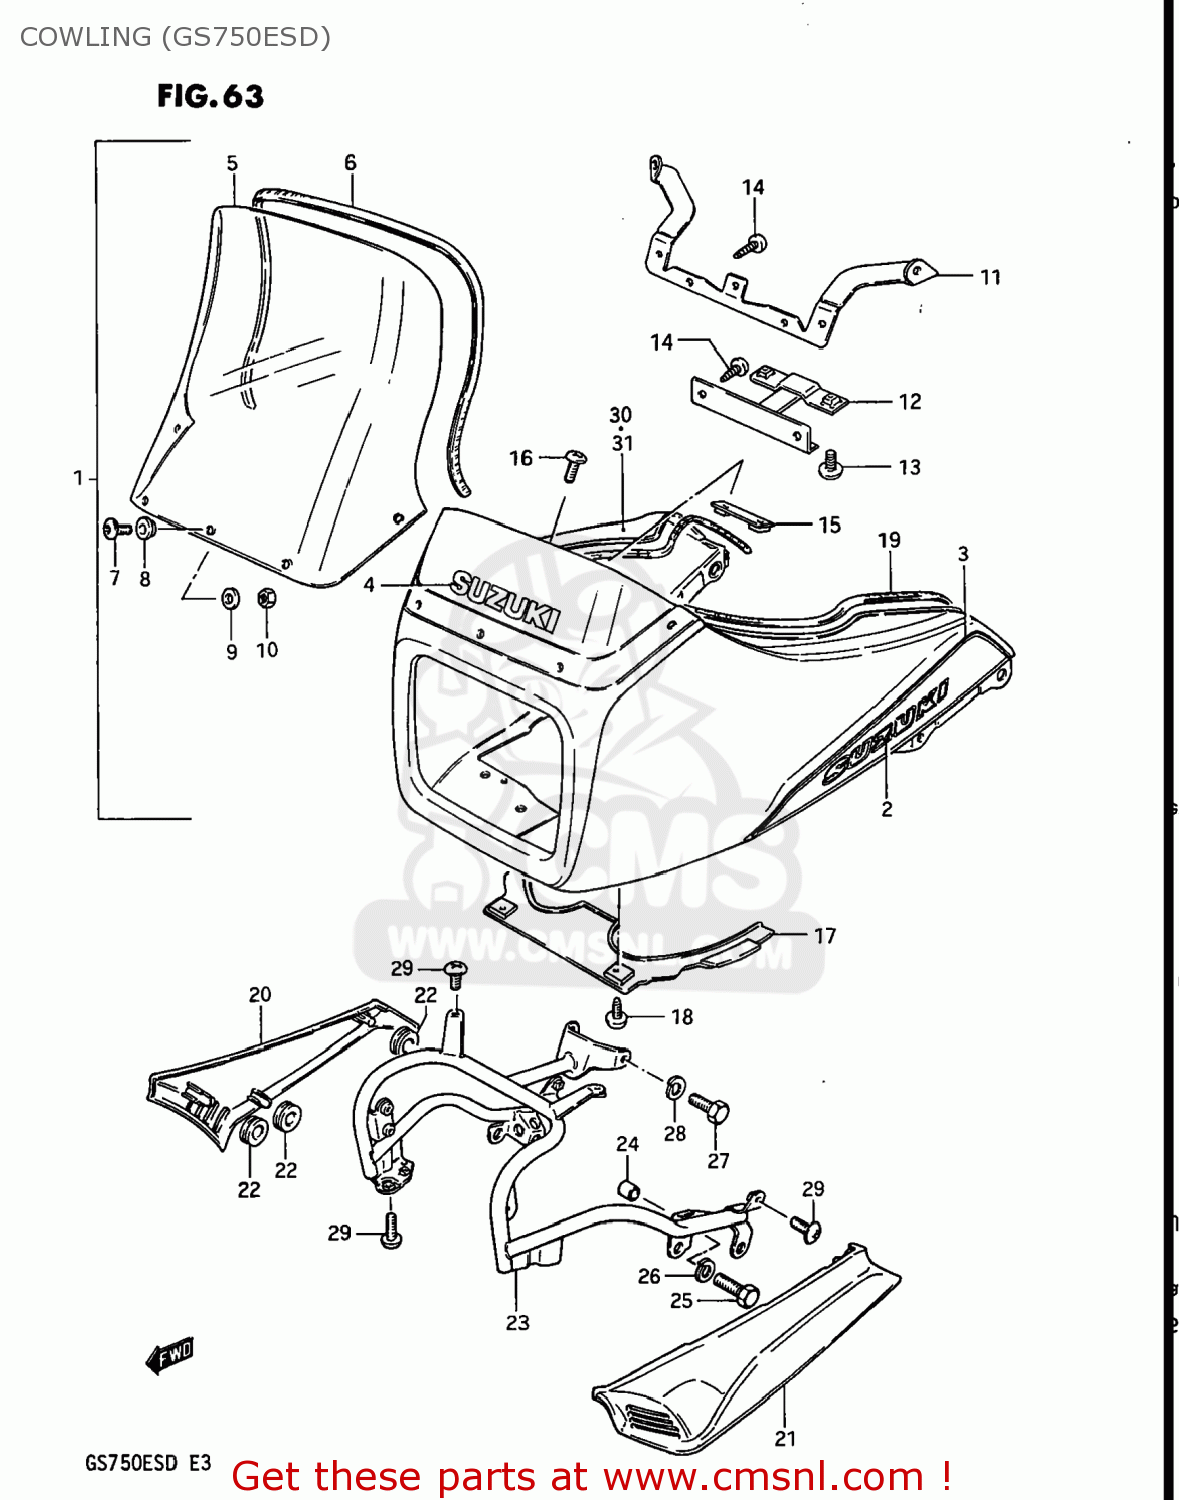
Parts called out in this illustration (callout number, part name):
1	COWLING ASSEMBLY,BODY
2	EMBLEM
3	TAPE SET,COWLING
4	EMBLEM,HEADLAMP
5	WINDOW,COWLING
6	MOLDING
7	SCREW
8	CUSHION
9	WASHER
10	NUT
11	BRACE,COWLING,UPPER
12	BRACE,COWLING,LOWER
13	SCREW RH & LH
14	SCREW
15	BRACKET
16	SCREW
17	MOLDING,FUEL TANK
18	COVER,COWLING,LOWER
19	SCREW
20	COVER,COWLING,RIGHT
21	COVER,COWLING,LEFT
22	CUSHION
23	BRACE,COWLING
24	SPACER,COWLING
25	BOLT (8X30)
26	LOCK WASHER
27	BOLT
28	LOCK WASHER
29	SCREW 6X12
30	TAPE,RIGHT
31	TAPE,LEFT
